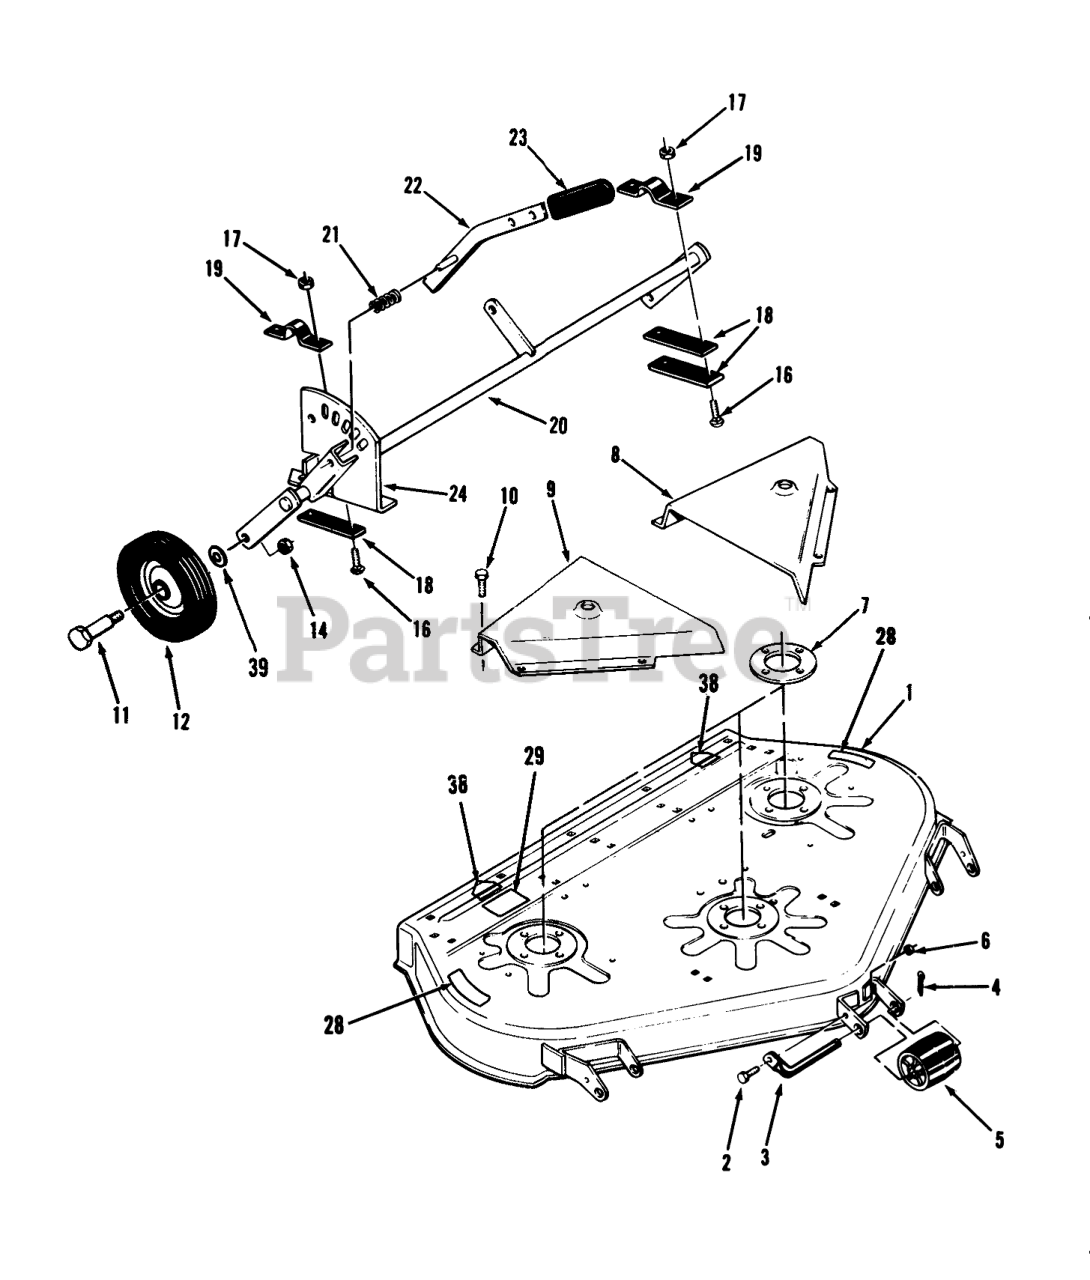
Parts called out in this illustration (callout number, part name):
1	Deck-Mower
2	SCREW-HH
3	ROLLER-SHAFT
4	PIN-COTTER
5	ROLLER ASSY
6	NUT-LOCK, NI
7	PLATE-SPINDLE
8	Belt Cover LH
9	Belt Cover RH
10	Bolt
11	BOLT-SHOULDER
12	WHEEL ASM
14	NUT-HEX
16	BOLT-CARR
17	NUT-LOCK, NI
18	Bar
20	Gage Wheel Support
21	SPRING-COMPRESSION
22	Lever
24	Quadrant
28	DECAL - DANGER
29	DECAL-HEIGHT & BELT
38	DECAL-DANGER
39	WASHER
